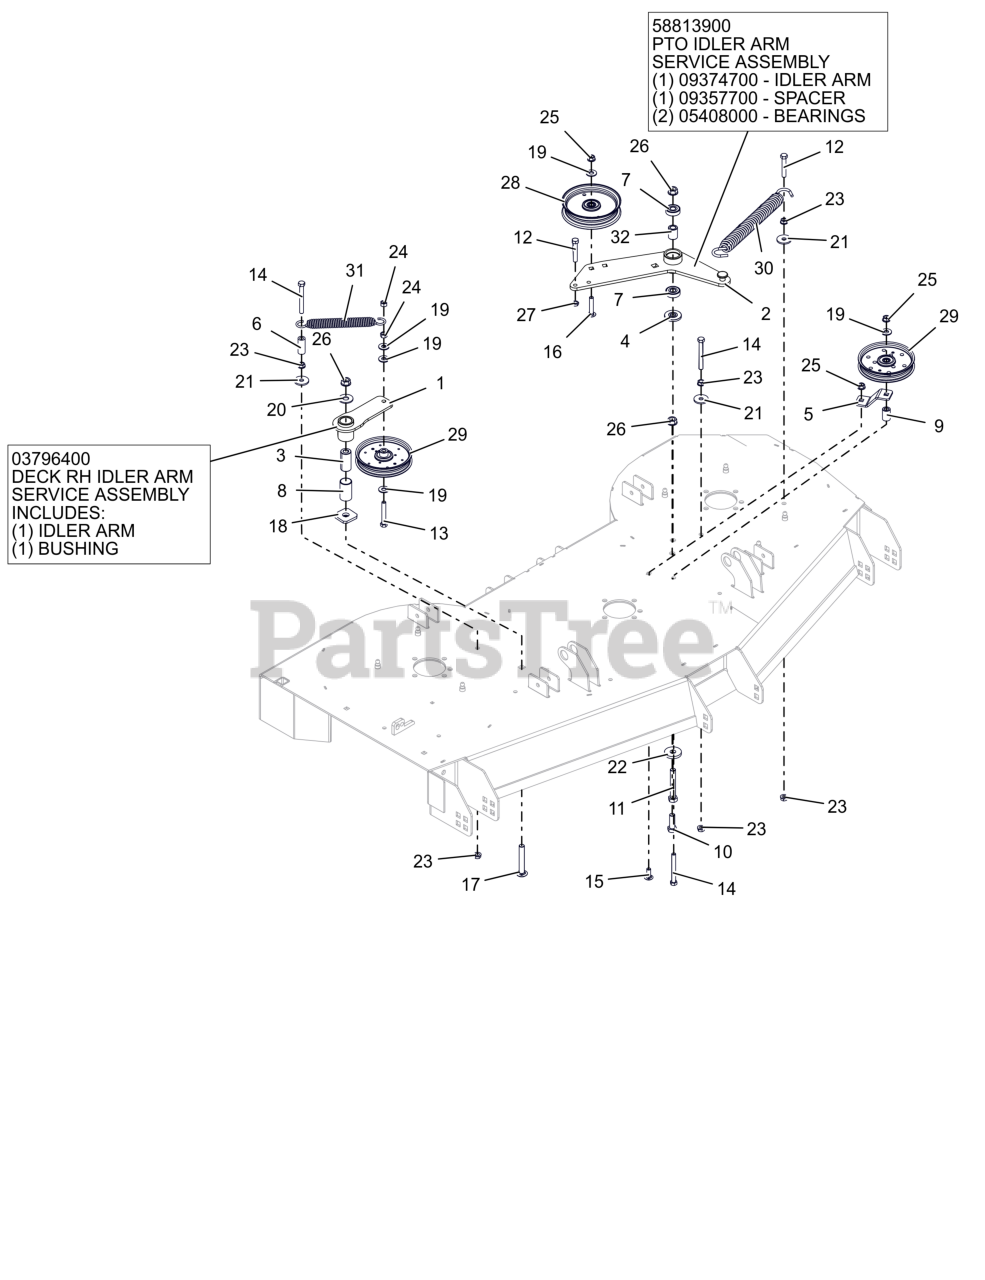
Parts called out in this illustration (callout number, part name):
1	WMT, IDLER ARM - BLACK
2	WLDMT, IDLER ARM PT660
3	BSHG, SPCR .502X.997X2.03 PM
4	SPACER, IDLER ARM
5	PTO FIXED IDLER MTG BRKT -RED
6	HOSE, .38 X 1.65
7	BRG-BALL .500X1.38X.437
8	BSHG, 1.00X1.125X1.937
9	BUSHING, SLV .380X.750X1.190
10	BLT,HEX .50-13X1.50 G5 ZCC
11	BLT,HEX .50-13X3.25 G5 ZCC
12	BLT,HEX .38-16X2.25 G5 ZCC
13	BLT, HEX .38-16X2.50 G5 ZCC
14	BLT, HEX .38-16X3.25 G5 ZCC
15	BLT,RHSSN .38-16X1.00 G5 ZCC
16	BLT,RHSSN.375-16X2.00 G5 ZCC
17	BTL,RHSSN .500-13 X 3.25 G5 ZCC
18	WSHR-FLT .640X1.75X.250
19	WSHR,FLT .438X1.00X.083 ZCC
20	WSHR,FLT .563X1.375X.109 ZCC
21	WSHR,FLT .406X1.375X.135 ZCC
22	WSHR-FL-STL 0.557X1.625X0.25 ZCC
23	NUT, SPNLK-FLG .38-16 G5 ZCC
24	NUT-LK-CTR .38-16 ZC120
25	NUT-LK-CTR-FLG .375-16 GF ZCC
26	NUT-LK-CTR-FLG .500-13 GG ZCC
27	NUT-JAM .375-16 G2 ZCC
28	IDLER- FLAT - 5.00" X .75"
29	IDLER- 5" FLANGED
30	SPRING, EXTENSION
31	SPRING- EXTENSION
32	SPACER .510 X .867 X 1.1485
